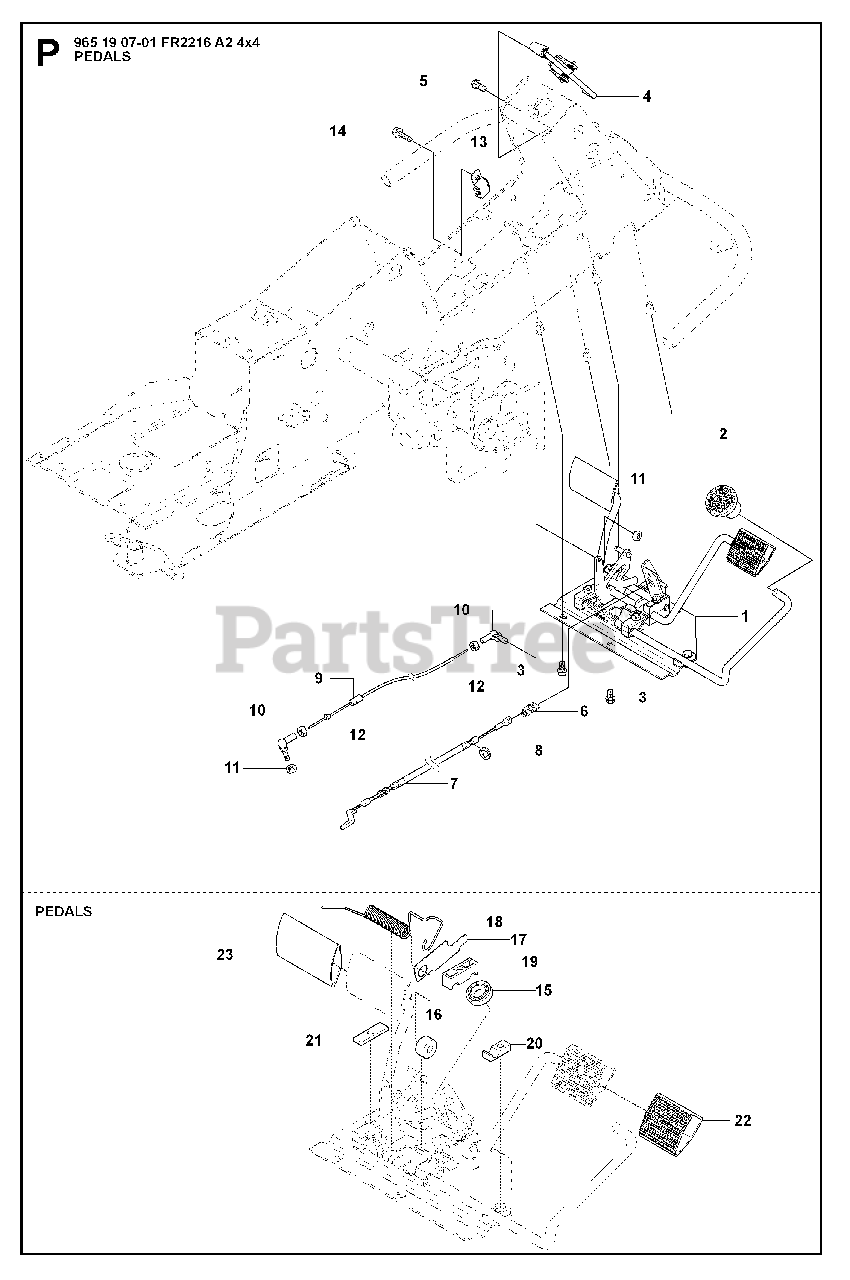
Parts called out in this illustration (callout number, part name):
1	PEDAL ASSEMBLY
2	KNOB
4	BRAKE LEVER ASSY
7	RP WIRE
9	%WIRE
10	CONNECTOR
11	LOCKNUT M5
13	BRACKET
15	BALL BEARING 6002-2RS1
16	ROLLER
17	PLATE
18	SPRING
19	PEDAL SHAFT CLAMP
20	SUPPORT
21	PLATE
22	PEDAL RUBBER
23	PEDAL RUBBER, SF
